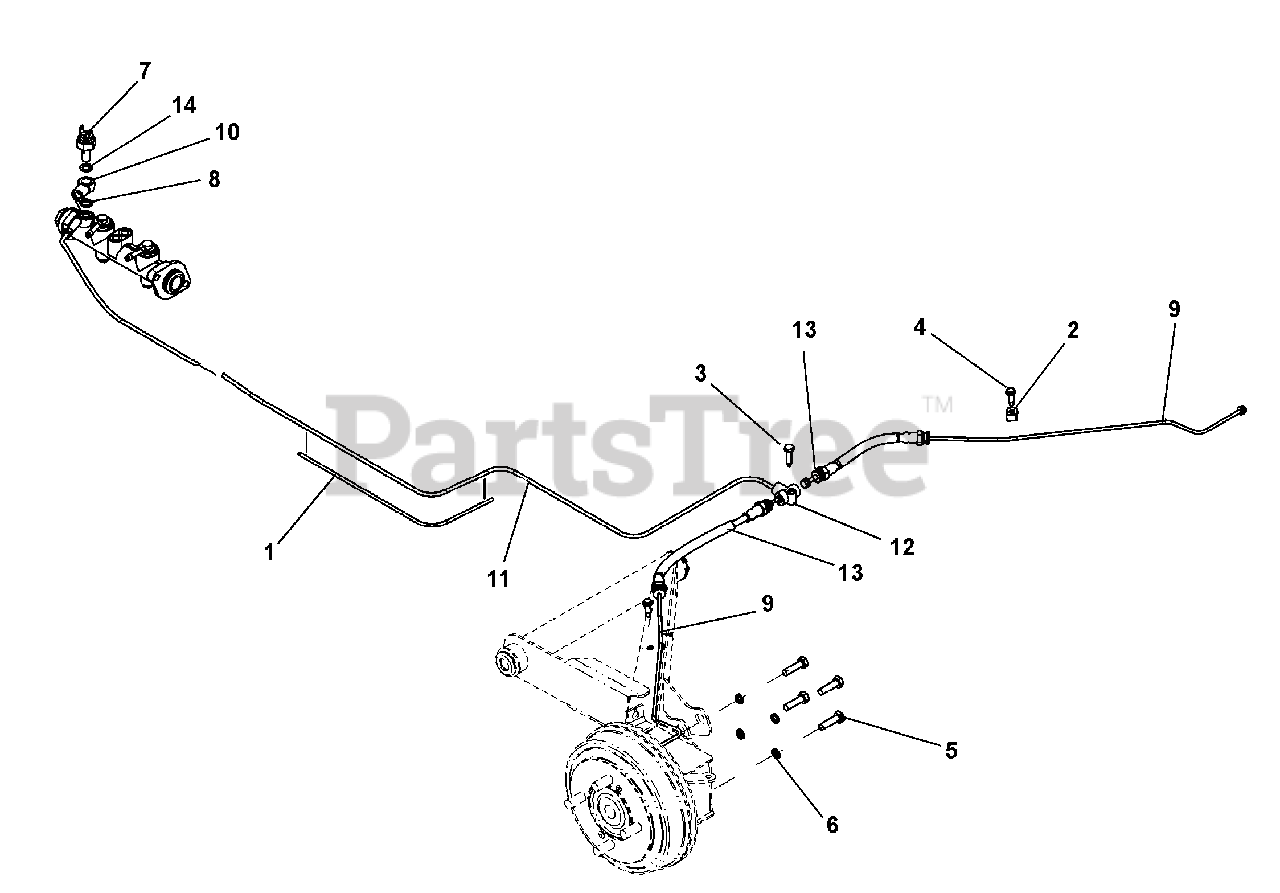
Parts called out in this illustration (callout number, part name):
1	CORRUGATED LOOM, .125 ID
2	WIRING/TUBE CLIP FOR 1/4 OD
3	SCREW HHC SELF-TAP 1/4-20X 1
4	HH DRILL SCREW 1/4 X 3/4LG
5	HHCS M8X1.25X30 GR10.9 YLW PLT
6	WSHR-LK M8 YWZC
7	BRAKE SWITCH, HIGH PRESSURE
8	WASHER, COPPER, 3.5 MM
9	REAR, BRAKE HARD LINE
10	BULK HEAD FLOW THROUGH
11	BRAKE, LINE MAIN
12	FITTING 3 WAY HYD.
13	REAR RUBBER BRAKE LINE
14	MSTR CYL CPPR WSHR 16X10X1.5MM
